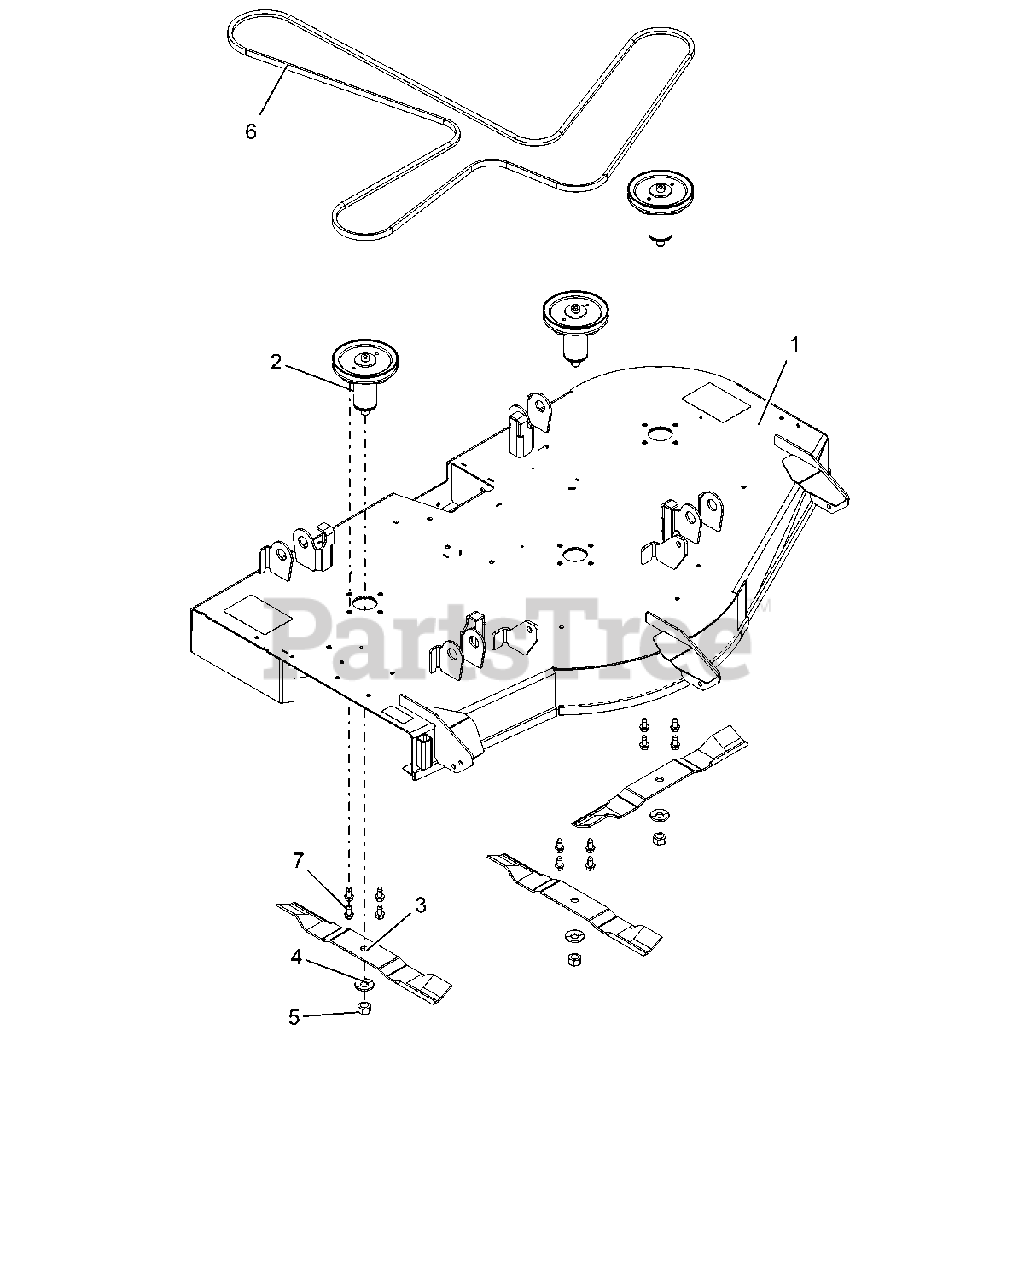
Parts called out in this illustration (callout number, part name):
1	WLDMT, DECK 52"
2	ASM, SPINDLE 4.75" DIA.
3	BLADE, 18" - 20 DEG .5 OFFSET
4	WSHR, BLVL .63X1.625X.14
5	NUT-HEX .62-18 YWZC
6	V-Belt, HA-WRAPPED CLUTCHING (NO RUBBER BLEED THRU)
7	SCR-TAP .38-16X.75 HWH TR YWZ
